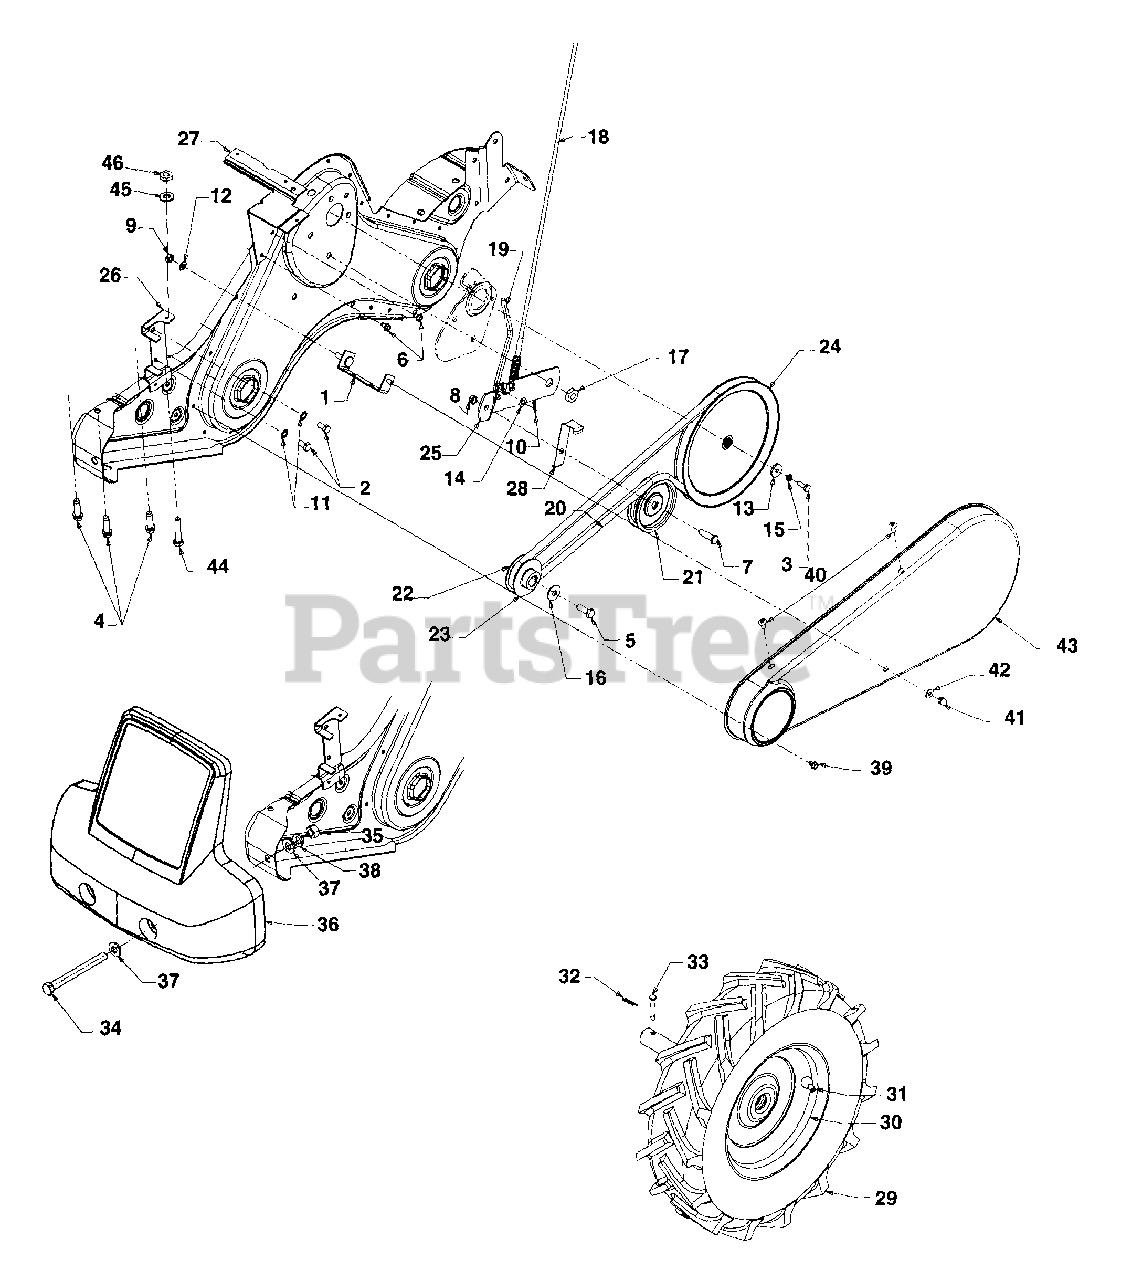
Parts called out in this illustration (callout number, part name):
1	Belt Cover Brkt. Ass'y
2	Hex Bolt 5/16-24 x .62" Lg.
3	Hex Bolt 1/4-28 x .75" Lg.
4	Hex Wash. TT-Sems Screw 3/8-16 x 1.250" Lg.
5	Hex Bolt 3/8-24 x 1.00
6	Hex Wash. Hd. S-Tap Scr.
7	Hex Cap Screw 3/8-16 x 1.25
8	Ctr. Lock Jam Nut 3/8-16
9	Hex Nut 5/16-18
10	Internal Cotter Pin
11	Hairpin Clip
12	L-Wash. 5/16" I.D.
13	Fl-Wash. 1/4 I.D. x .93 O.D.
14	Spring-Wash. .317 x .625 O.D. x .099
15	L-Wash. 1/4" I.D.
16	Bell-Wash. .396 x 1.140 x .095
17	Shld. Nut 7/16-20
18	Clutch Cable
19	Idler Pulley Rod
20	Belt: 4L x 58.16 Lg.
21	Fl-Idler w/Flange 3.75" O.D.
22	Outer Engine Pulley Half
23	Inner Engine Pulley Half
24	Input Pulley
25	Idler Bracket
26	Belt Keeper Brkt.
32	Clevis Pin
33	Internal Cotter Pin
34	Hex Bolt 1/2-13 x 5.00" Lg.
35	Hex Nut 1/2-13 Thd.
36	Counterweight
37	Fl-Wash. .510" I.D. x 1.0" O.D.
38	L-Wash. 1/2" Lg.
39	Hex Screw 1/4-20 x .375" Lg.
40	Screw 1/4-14 x .625" Lg.
41	Acorn Lock Nut
42	Fl-Washer 1/4 x .620" Lg.
44	Hex Bolt 5/16-18 x 1.50" Lg.
45	Bell-Wash. .340 I.D. x .872 O.D.
46	Nut:Hex 5/16-18
